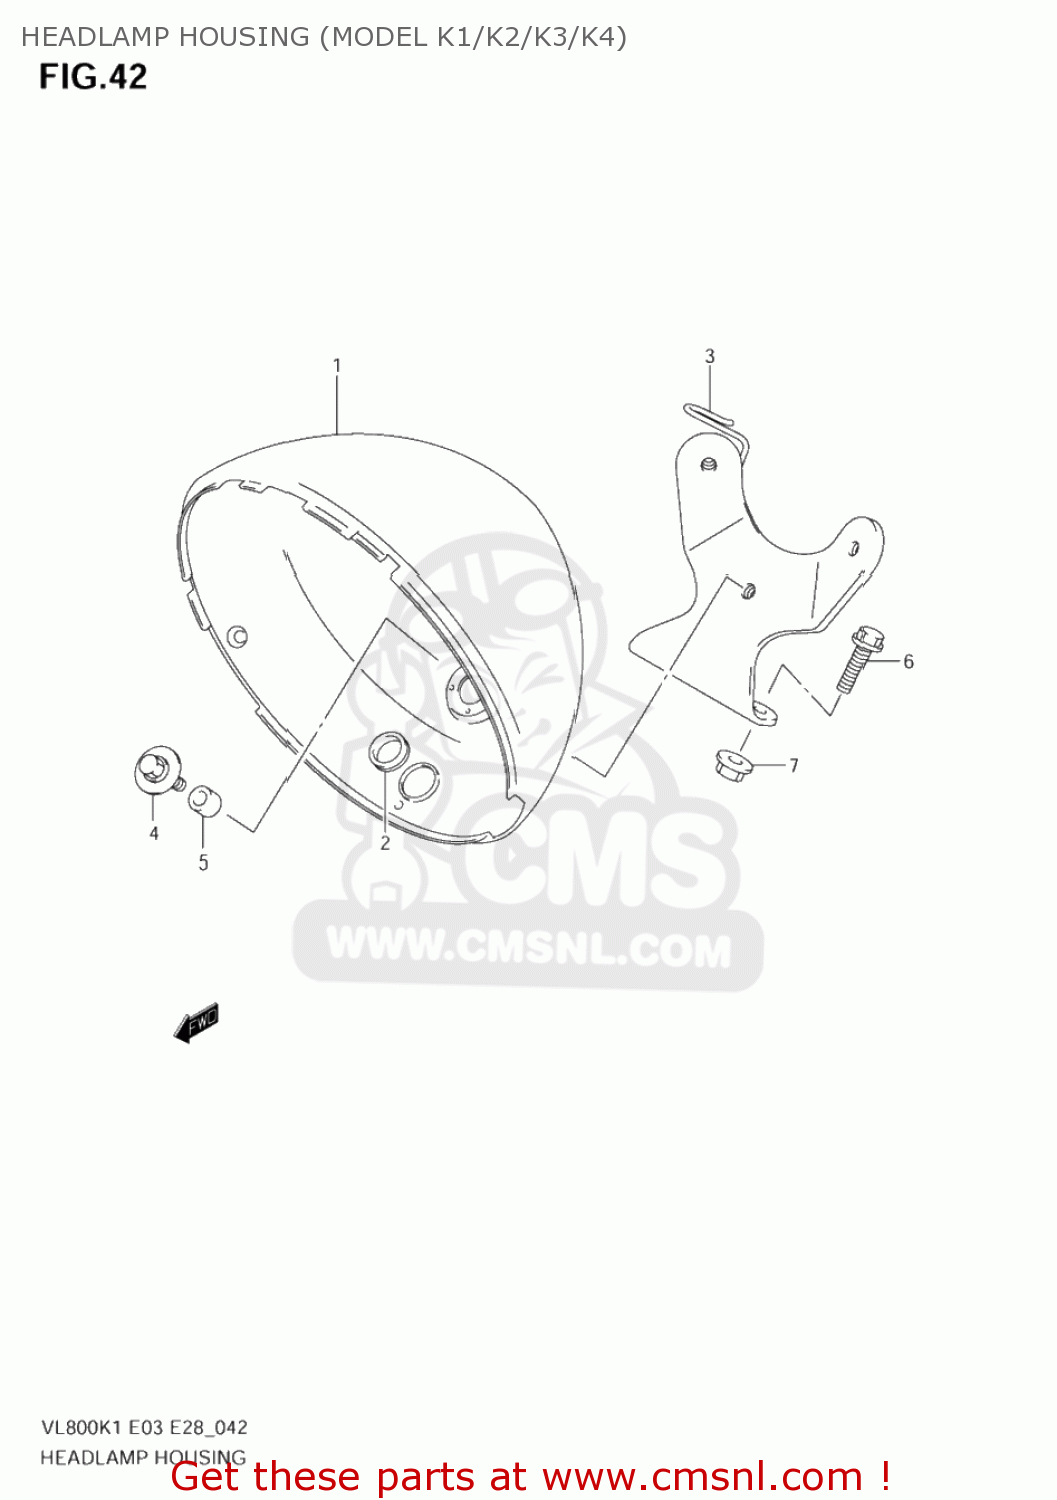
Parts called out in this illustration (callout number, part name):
1	HOUSING,HEADLAMP
2	MOLDING,HOUSING
3	BRACKET COMP,H
4	BOLT(6X25)
5	SPACER(6.8X12X11)
6	BOLT
7	NUT
